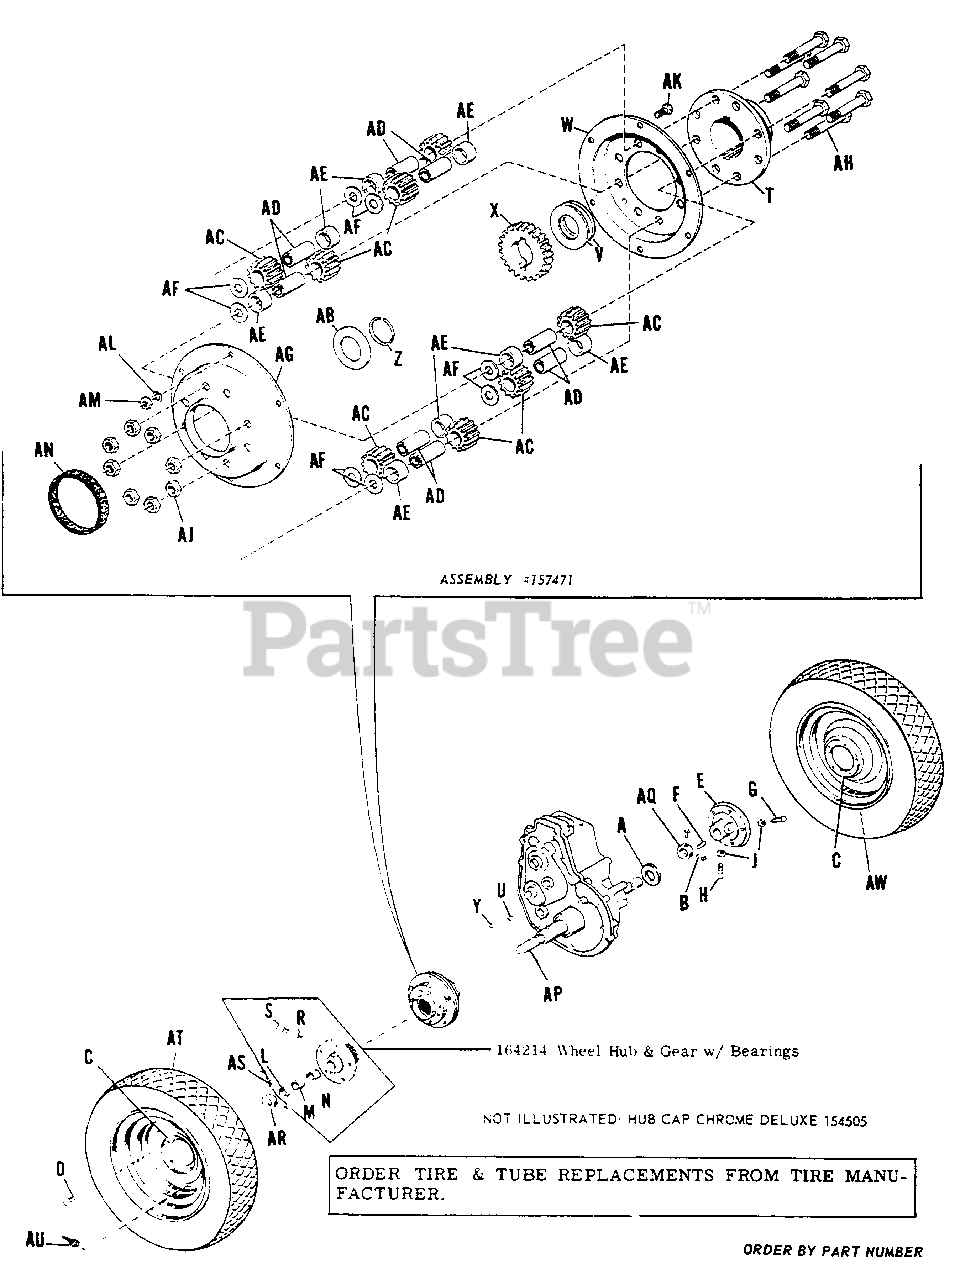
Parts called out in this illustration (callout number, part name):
B	Set Screw, 5/16"-18 x 3/8" lg. Sq. Hd. Cup Pt.
C	Drive Wheel
E	L.H. Wheel Hub
G	Set Screw, 3/8"-16 x 1-1/2" lg. Sq. Hd. Cup Pt.
H	Set Screw, 3/8"-16 x 1" lg.Sq. Hd. Cup Pt.
J	Hex. Jam Nut, 3/8"-16
M	Nylon Bearing
R	Nylon Plug
S	Set Screw, 7/16"-20 x 1/2" lg. Soc.Hd.
T	Differential Carrier
V	Axle Washer
W	Differential Cover
X	Differential Gear
Y	Hi-Pro Key
Z	Retaining Ring
AB	Axle Washer
AC	Differential Pinion
AD	Pinion Differential Spindle
AE	Differential Spacer
AF	Plain Washer
AG	Differential Cover
AH	Hex. Cap Screw, 3/8"-16 x 2-1/2"
AJ	Full Lock Hex. Nut, 3/8"-16
AK	Hex. Cap Screw, 1/4"-20 x 5/8"
AL	Lock Washer, 1/4"
AM	Full Hex. Nut, 1/4"-20
AN	Differential Cover Seal
AQ	Axle Collar
AR	Axle Collar
AS	Set Screw,5/16"-18 x 3/8" Sq.Hd. Cup Pt.
AT	Tire 8 x 12
AU	Valve Stem
AU	Wheel & Tire Assembly
AW	Tube (For Service Only)
